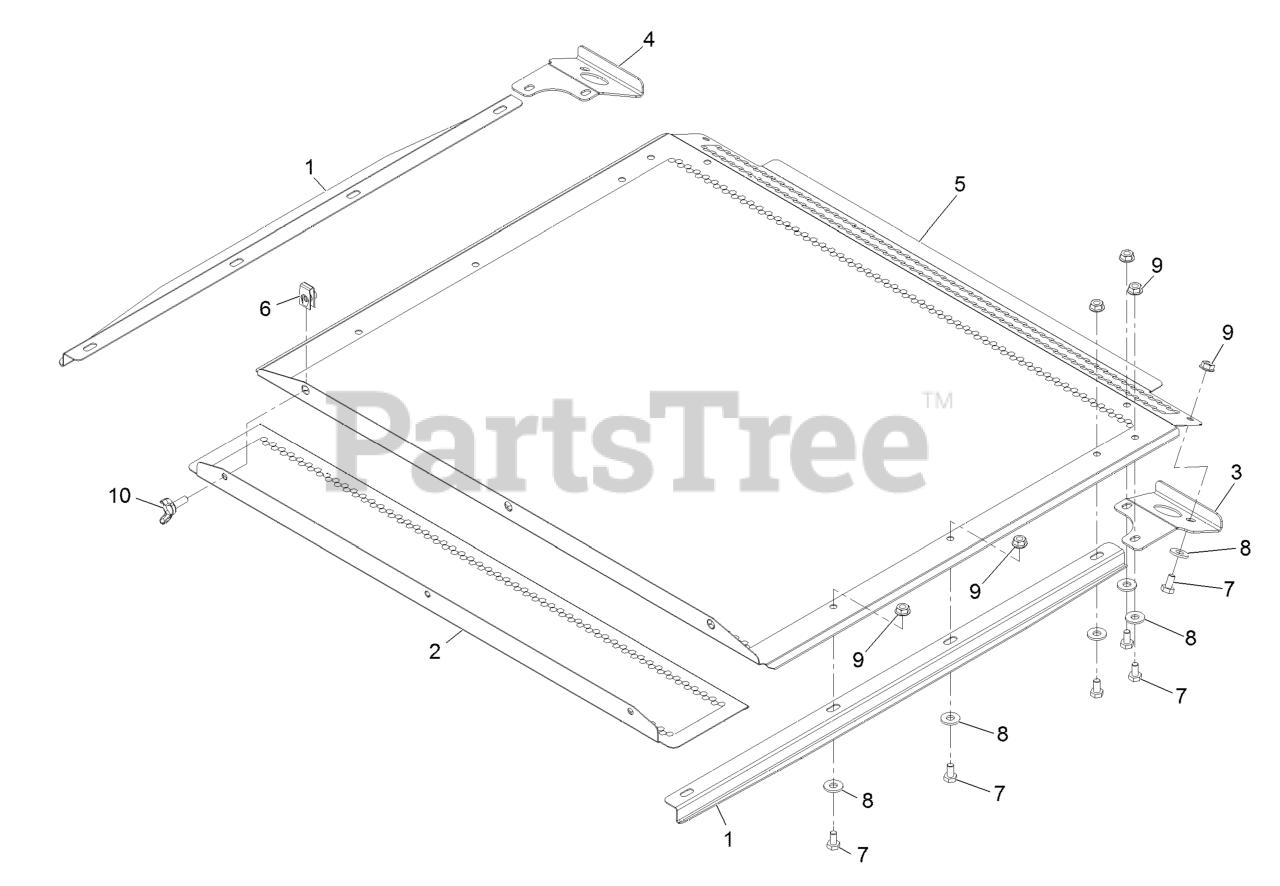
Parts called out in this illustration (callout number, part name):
1	GUIDE-SCREEN
2	PANEL-SCREEN, REMOVABLE
3	HANDLE-SCREEN, LH
4	HANDLE-SCREEN, RH
5	PANEL-SCREEN, HOPPER
6	Nut-Retainer-Panel 1/4-20
7	SCREW-HH
8	WASHER-FLAT
10	SCREW-WING
